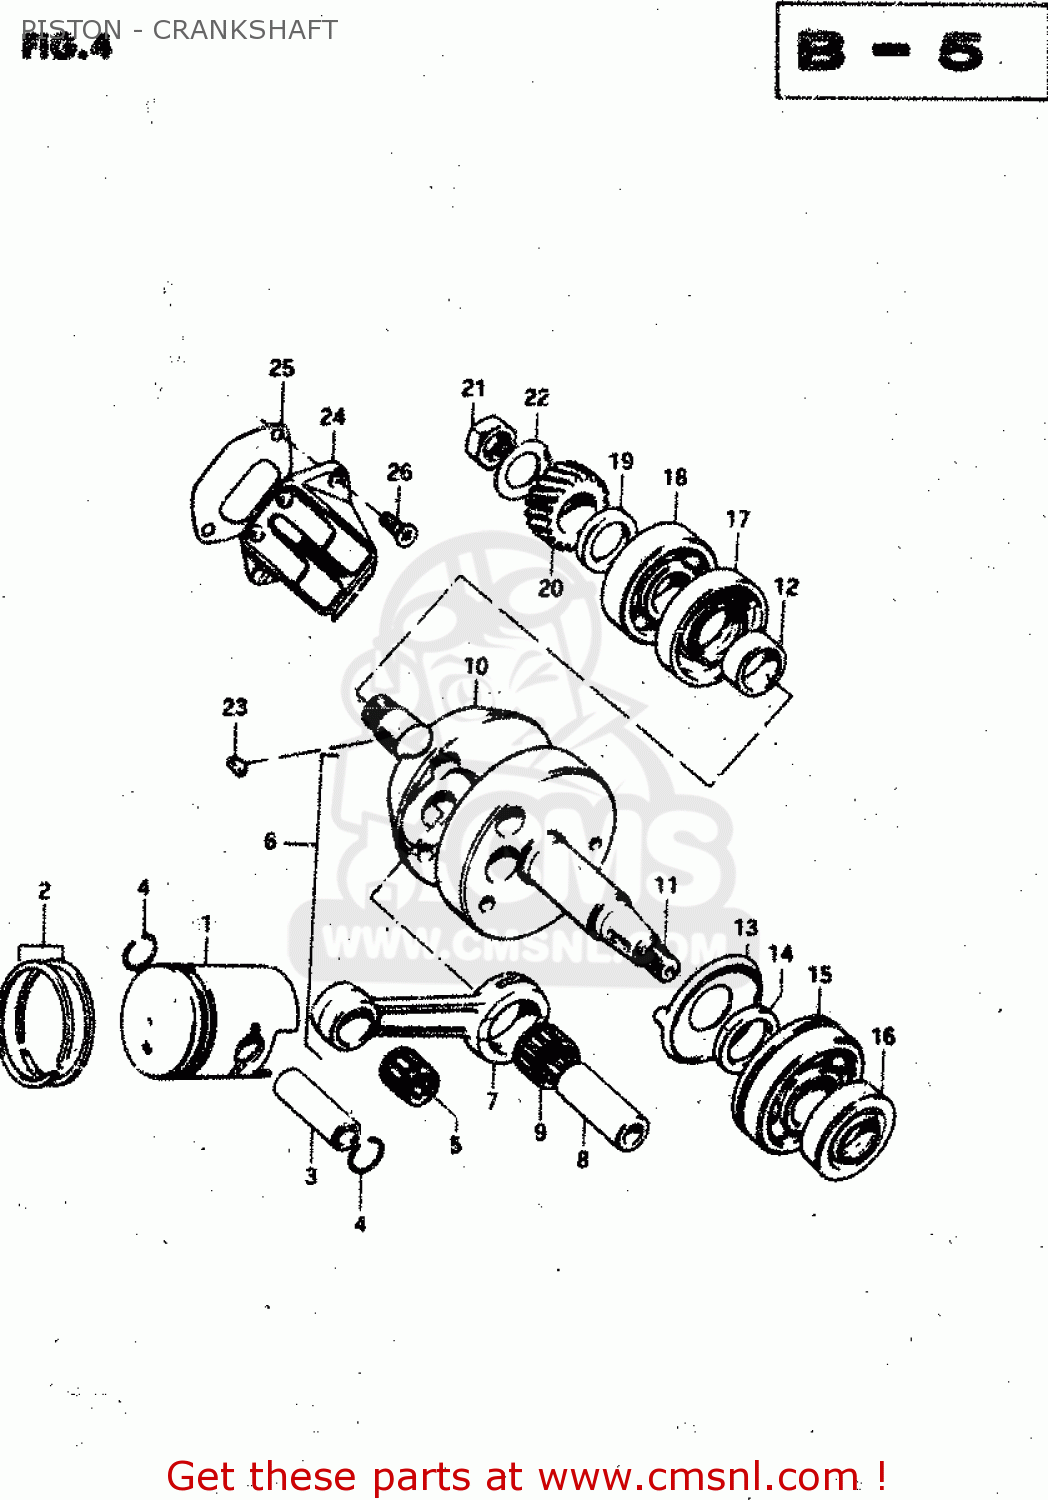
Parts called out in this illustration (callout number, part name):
1	PISTON
2	RING SET,PISTON
3	PIN,PISTON
4	RING,SNAP
5	BEARING
6	CRANKSHAFT SET
7	CONNECTING ROD
8	PIN,CRANK
9	BEARING
10	CRANKSHAFT, RH
11	CRANKSHAFT, LH
12	SPACER(17X23X9)
13	PLATE,CSHAFT OIL GUIDE
14	SPACER(20X28X4.5)
15	BEARING(20X47X14)
16	SEAL,OIL(19.6X37X8)
17	SEAL,OIL(22.2X47X8)
18	BEARING
19	SPACER(17.2X27X4.5)
20	GEAR,PRIMARY DRIVE NO.21
21	NUT
22	WASHER
23	KEY
24	REED VALVE ASSY
25	GASKET
26	SCREW
